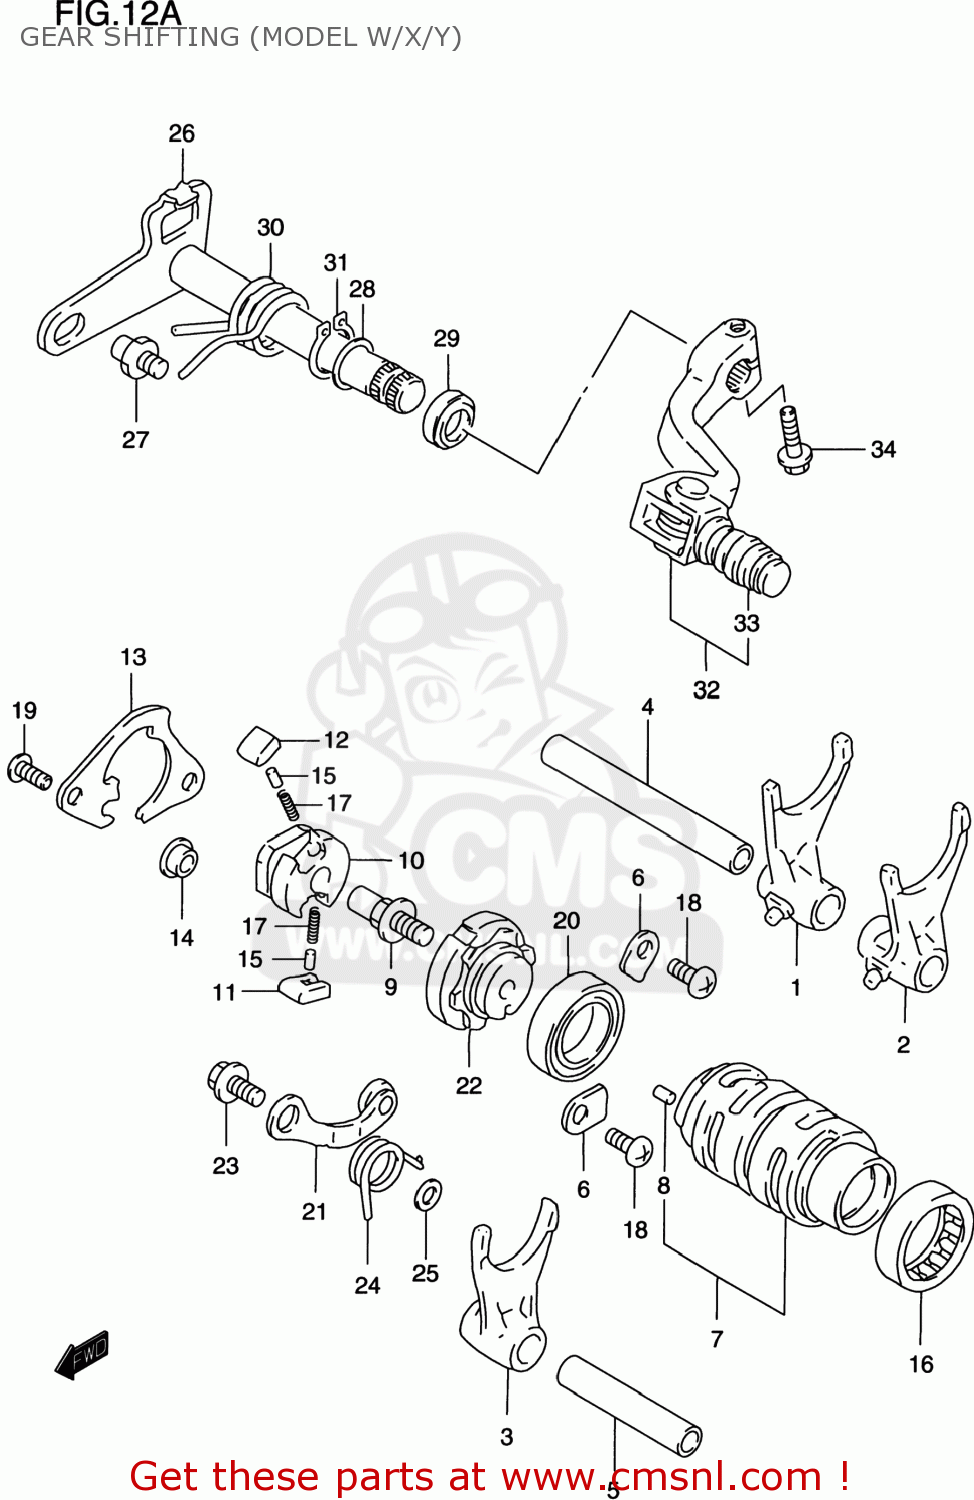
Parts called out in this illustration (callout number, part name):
1	FORK,GEAR SHIFT NO.1
2	FORK,GEAR SHIFT NO.2
3	FORK,GEAR SHIFT NO.3
4	SHAFT,GEAR SHIFT FORK
5	SHAFT,GEAR SHIFT FORK
6	RETAINER
7	CAM,GEAR SHIFT
8	PIN
9	PIN,SHIFT CAM DRIVEN GEAR
10	SHIFTER,GEAR SHIFT CAM
11	PAWL,GEAR SHIFT NO.1
12	PAWL,GEAR SHIFT NO.2
13	LIFTER,GEAR SHIFT PAWL
14	SPACER(7X10X5)
15	PIN(5X8)
16	BEARING(33X38X8)
17	SPRING
18	SCREW
19	SCREW
20	BEARING
21	STOPPER,SHIFT CAM
22	PLATE,SHIFT CAM STOPPER
23	BOLT(6X14.3)
24	SPRING
25	WASHER
26	SHAFT,GEAR SHIFT
27	STOPPER,SHIFT ARM
28	SHIM(14X20X1)
29	SEAL,OIL(14X22X6)
30	SPRING
31	CIRCLIP
32	LEVER ASSEMBLY,GEAR SHIFTING
33	RUBBER,GEAR SHIFT PEDAL
34	SCREW
